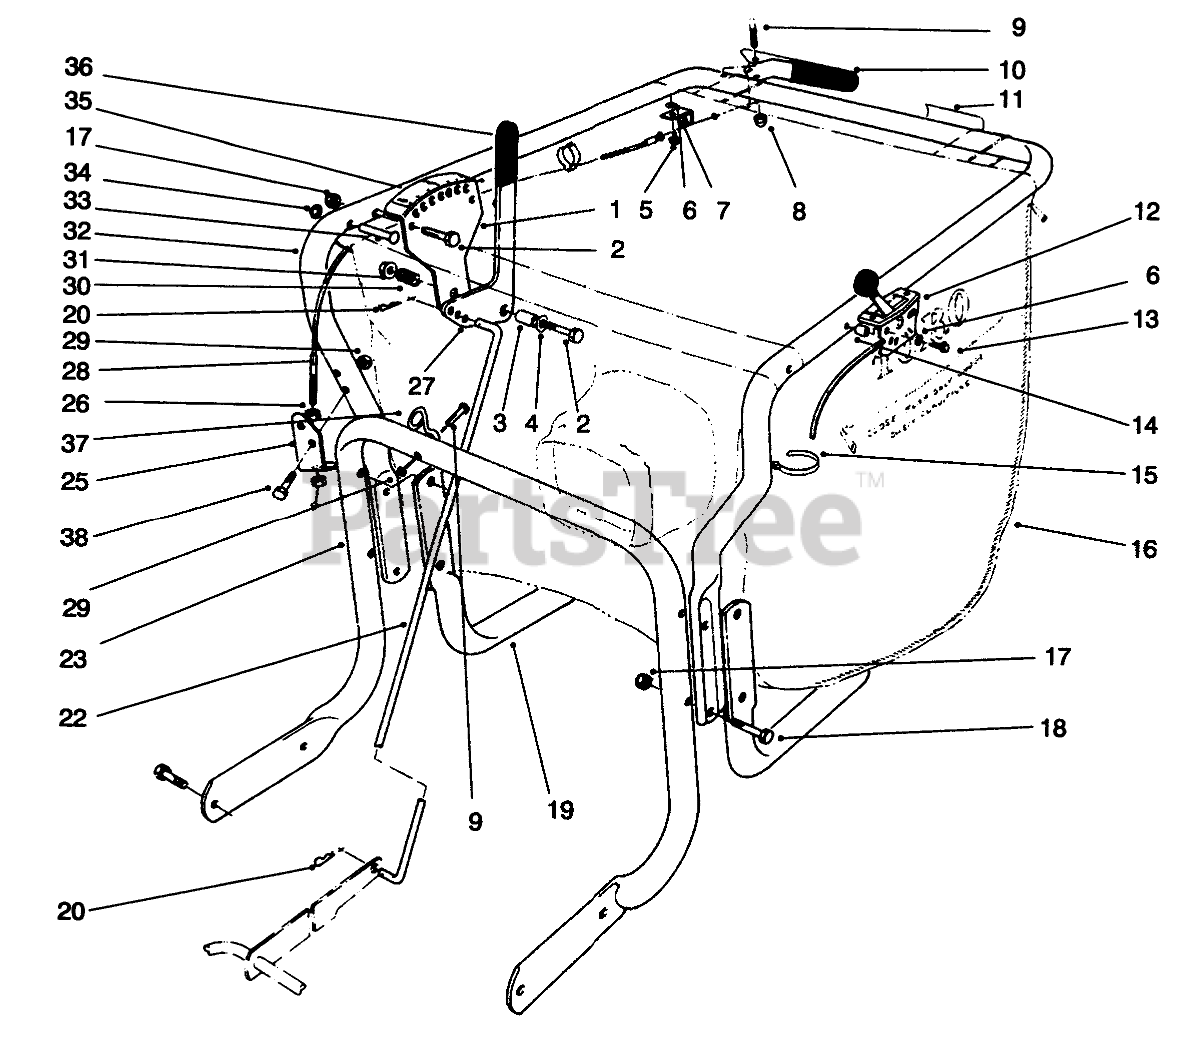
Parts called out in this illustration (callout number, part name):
1	Adjustment Bracket
2	SCREW-HH
3	SPACER
4	WASHER-FLAT
5	SCREW-HWH
6	WASHER-LOCK, EXT
7	RETAINING-CLIP
8	NUT-CAP
9	SCREW-HH
10	LEVER
11	DECAL-CONTROL, TRACTION
12	THROTTLE CONTROL
13	10-24 X 1 PAN HD SCR
14	SPACER
15	TIE-CABLE
16	VACUUM BAG
17	NUT-LOCK, NI
18	SCREW-HH
19	Support-Bag
20	PIN-COTTER
22	HEIGHT ADJ. ROD
23	HANDLE
25	MOUNT-BOWDEN, LOWER
26	NUT-KEPS
27	Handle-Adjustment
28	ASM - FORWARD CABLE
29	NUT-LOCK, NI
30	SPRING - COMPRESSION
31	NUT-HF
32	HANDLE-UPPER, VACUUM
33	RIVET
34	NUT-PUSH IN
35	DECAL-ADJUSTMENT, HEIGHT
36	GRIP-HANDLE
37	GUIDE-ROPE
38	SCREW-HH
